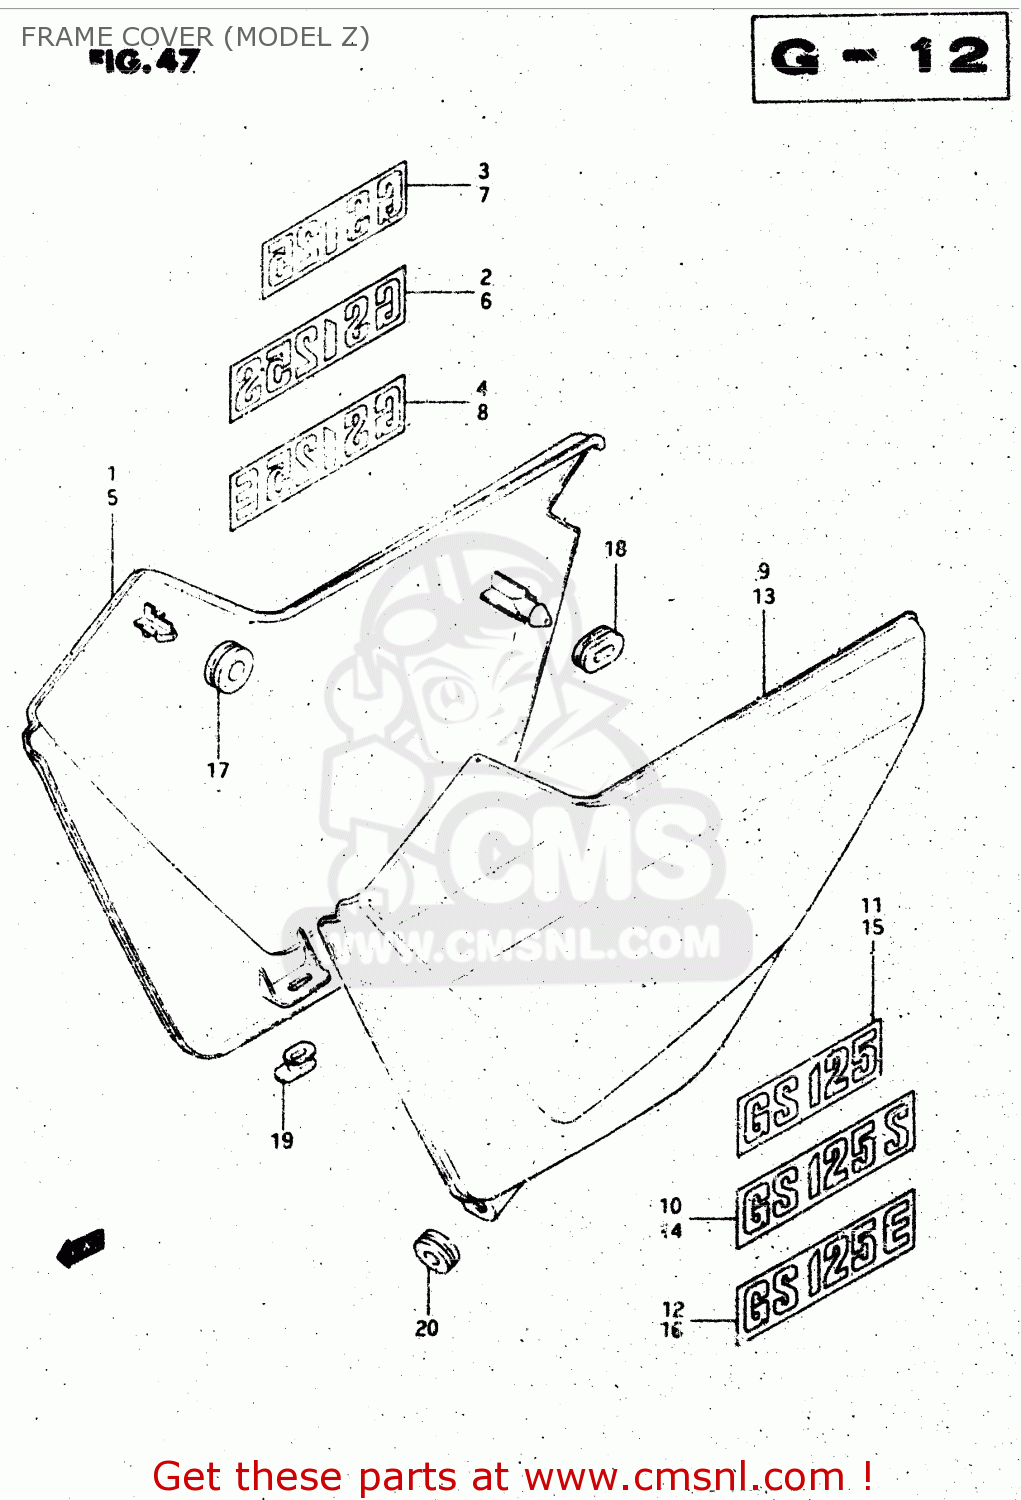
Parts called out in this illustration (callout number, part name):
1	COVER, FRAME RH (RED)
2	EMBLEM
3	EMBLEM (SILVER)
4	EMBLEM
5	COVER, FRAME RH (BLUE)
6	EMBLEM
7	EMBLEM (SILVER)
8	EMBLEM
9	COVER, FRAME LH (RED)
10	EMBLEM
11	EMBLEM (SILVER)
12	EMBLEM
13	COVER, FRAME LH (BLUE)
14	EMBLEM
15	EMBLEM (SILVER)
16	EMBLEM
17	CUSHION
18	CUSHION
19	CUSHION
20	CUSHION
